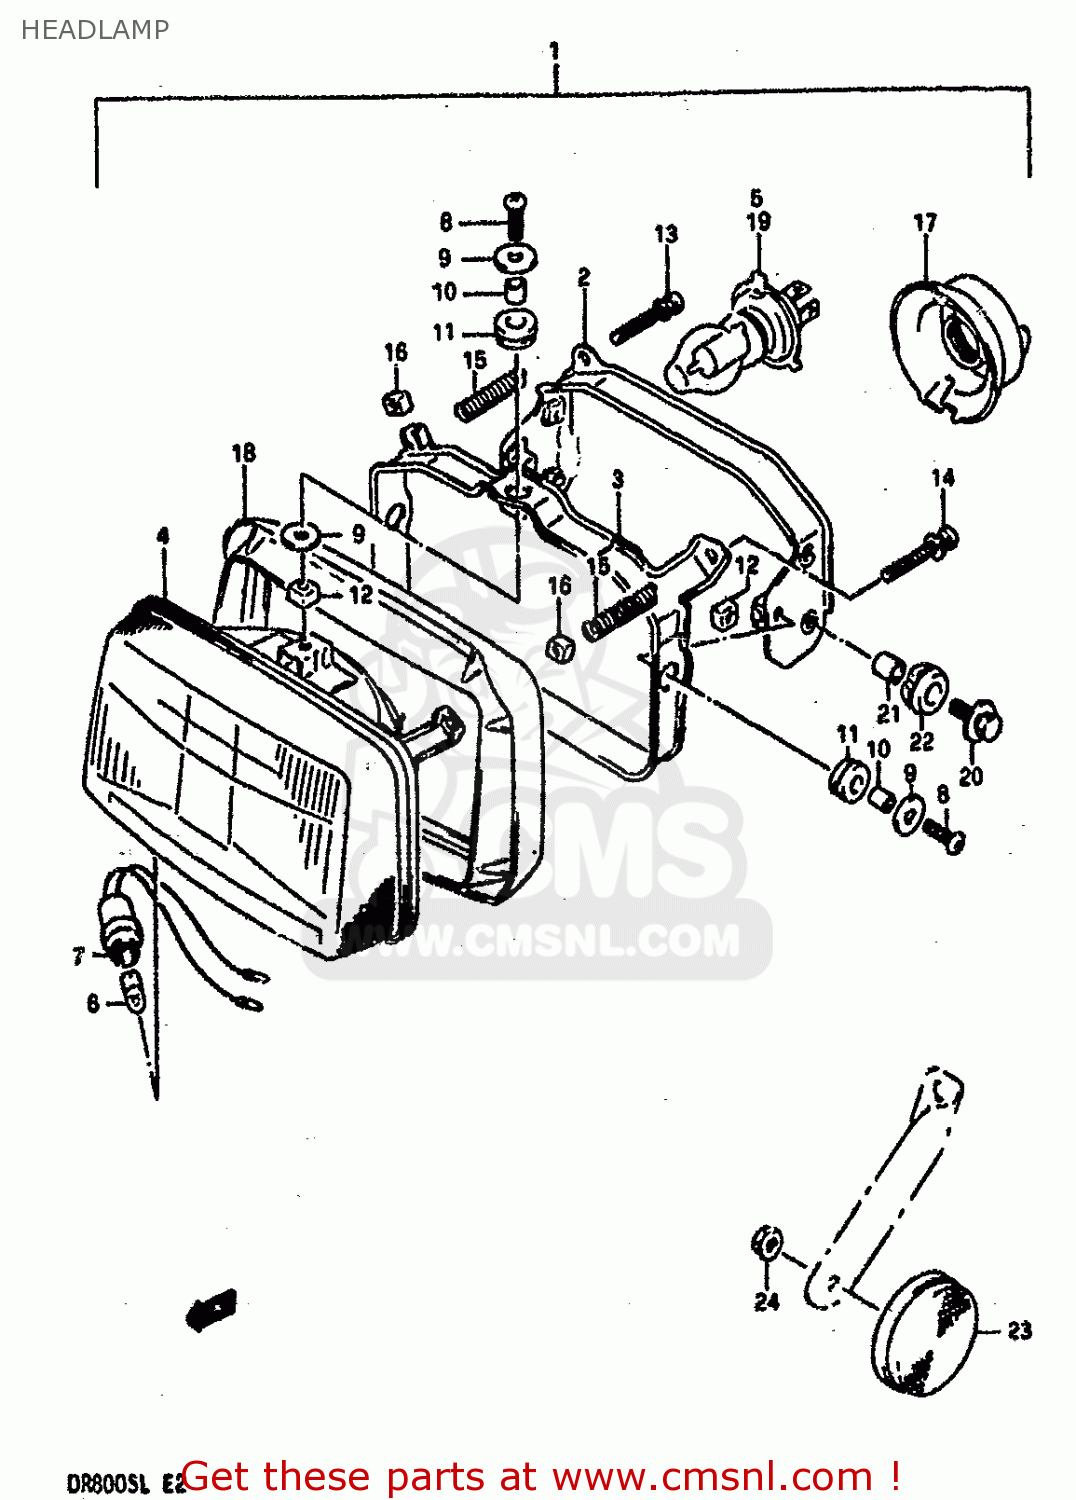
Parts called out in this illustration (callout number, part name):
1	HEADLAMP ASSY
2	HOUSING
3	RING
4	LAMP,UNIT
5	BULB (12V, 60/55W, H4)
6	BULB(12V4W)
7	SOCKET
8	SCREW (5X18)
9	WASHER
10	SPACER
11	CUSHION
12	NUT
13	SCREW
14	SCREW
15	SPRING
16	NUT
17	COVER,SOCKET
18	SHADE
19	BULB (12V, 60/55W, H4)
20	BOLT 6X20
21	SPACER (6.8X10X10)
22	CUSHION
23	REFLECTOR,REFLEX FR
24	NUT 5MM
